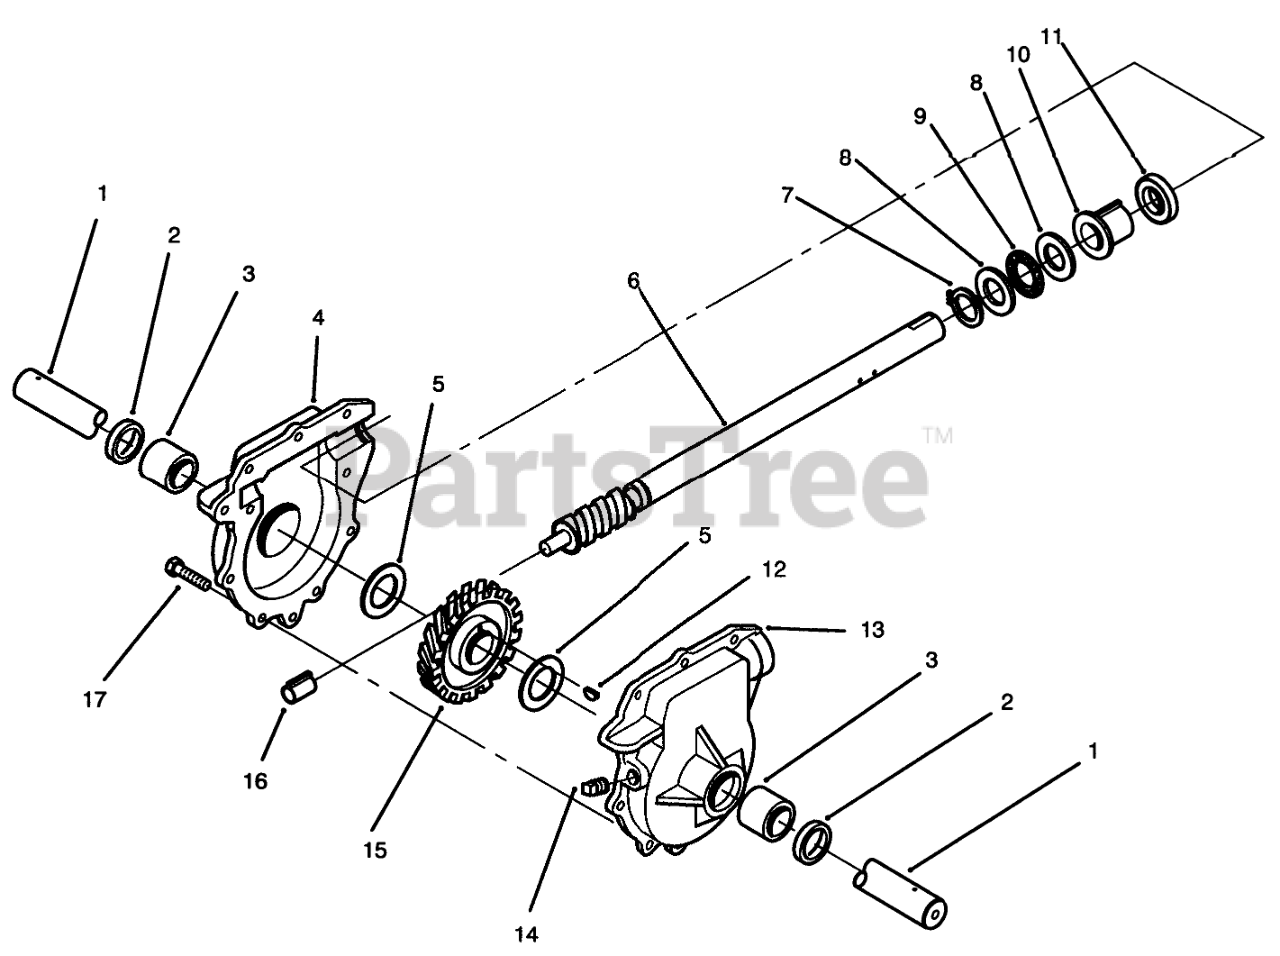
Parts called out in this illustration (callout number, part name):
1	SHAFT-AUGER
2	SEAL-OIL
3	BUSHING
4	Gearcase Assembly-R.H. (Incl. Ref. # 2-3)
5	WASHER-THRUST
6	SHAFT-IMPELLER
7	RING-RETAINING, Ext
8	WASHER-THRUST
9	BEARING-THRUST
10	BUSHING-INPUT
11	SEAL-OIL
12	KEY-WOODRUFF
13	Gearcase Assembly-L.H. (Incl. Ref. # 2-3)
14	PLUG-PIPE, SQH
15	GEAR-HELICAL
16	BUSHING-WORM
17	SCREW-HWH
